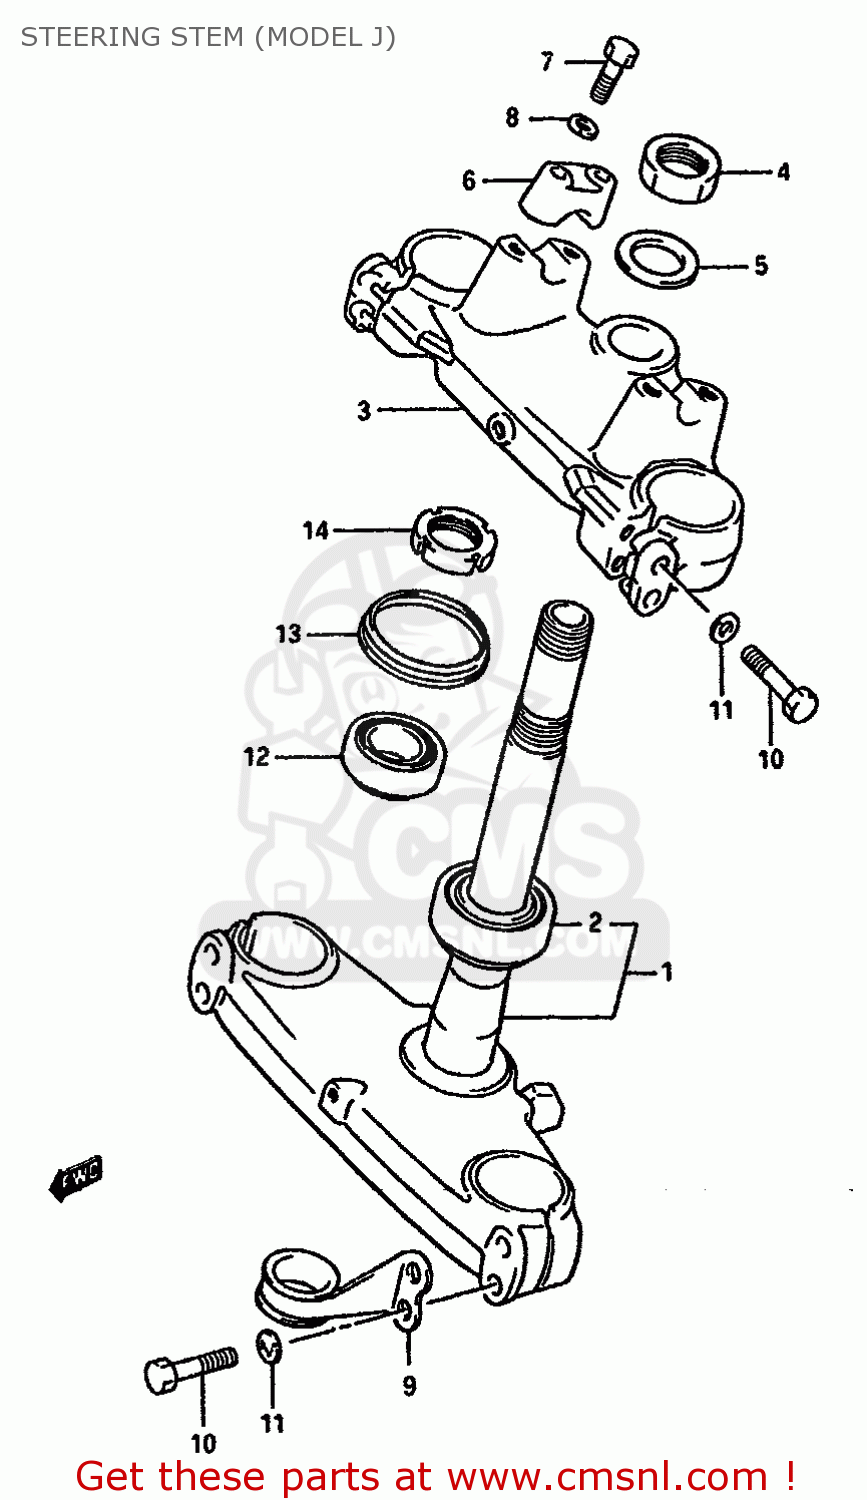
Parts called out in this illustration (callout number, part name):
1	STEM,STEERING
2	BEARING
3	HEAD,STEERING STEM
4	NUT,STEERING STEM
5	WASHER
6	HOLDER,HANDLEBAR
7	BOLT
8	LOCK WASHER
9	CLIP
10	BOLT 8X40
11	LOCK WASHER
12	TAPER,ROLLER BEARING
13	SEAL,STEERING UPR DUST
14	BOLT
15	LOCK WASHER
16	RACE,STEERING INNER (SUJ)
17	RACE,STEERING,OUTER,UPPER
18	BALL
19	SEAL,STEERING UPR DUST
20	NUT,STEERING STEM
